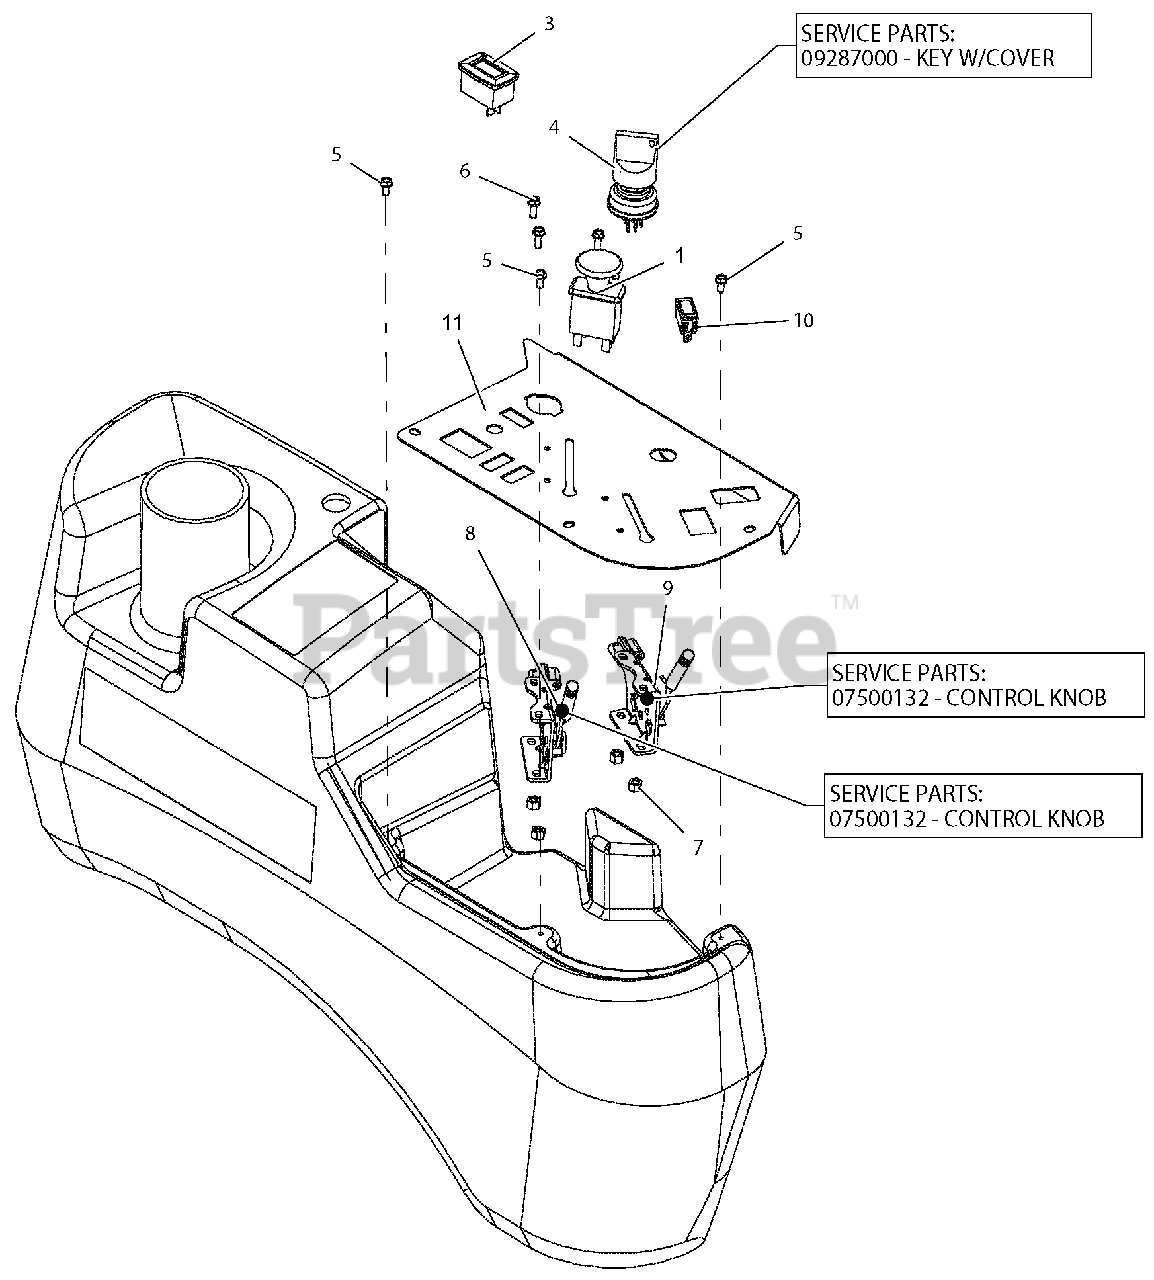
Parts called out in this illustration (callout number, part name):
1	SWITCH, CLUTCH
3	METER, HOUR W/MAINTENANCE
4	SWITCH, IGNITION
4	SERVICE PART: KEY W/COVER
5	SCR-MCH 10-24X.38 HWHSTAINLESS
6	@SCR-MCH 10-24X.50 HWH YWZC
7	NUT-LK-NYL #10-24 YWZC
8	CABLE, PRO-CONTROL THROTTLE
8	SERVICE PART: CONTROL KNOB
9	CABLE, THROTTLE 53"
9	SERVICE PART: CONTROL KNOB
10	LIGHT, INDICATOR
11	PANEL, CONTROL (BLACK)
